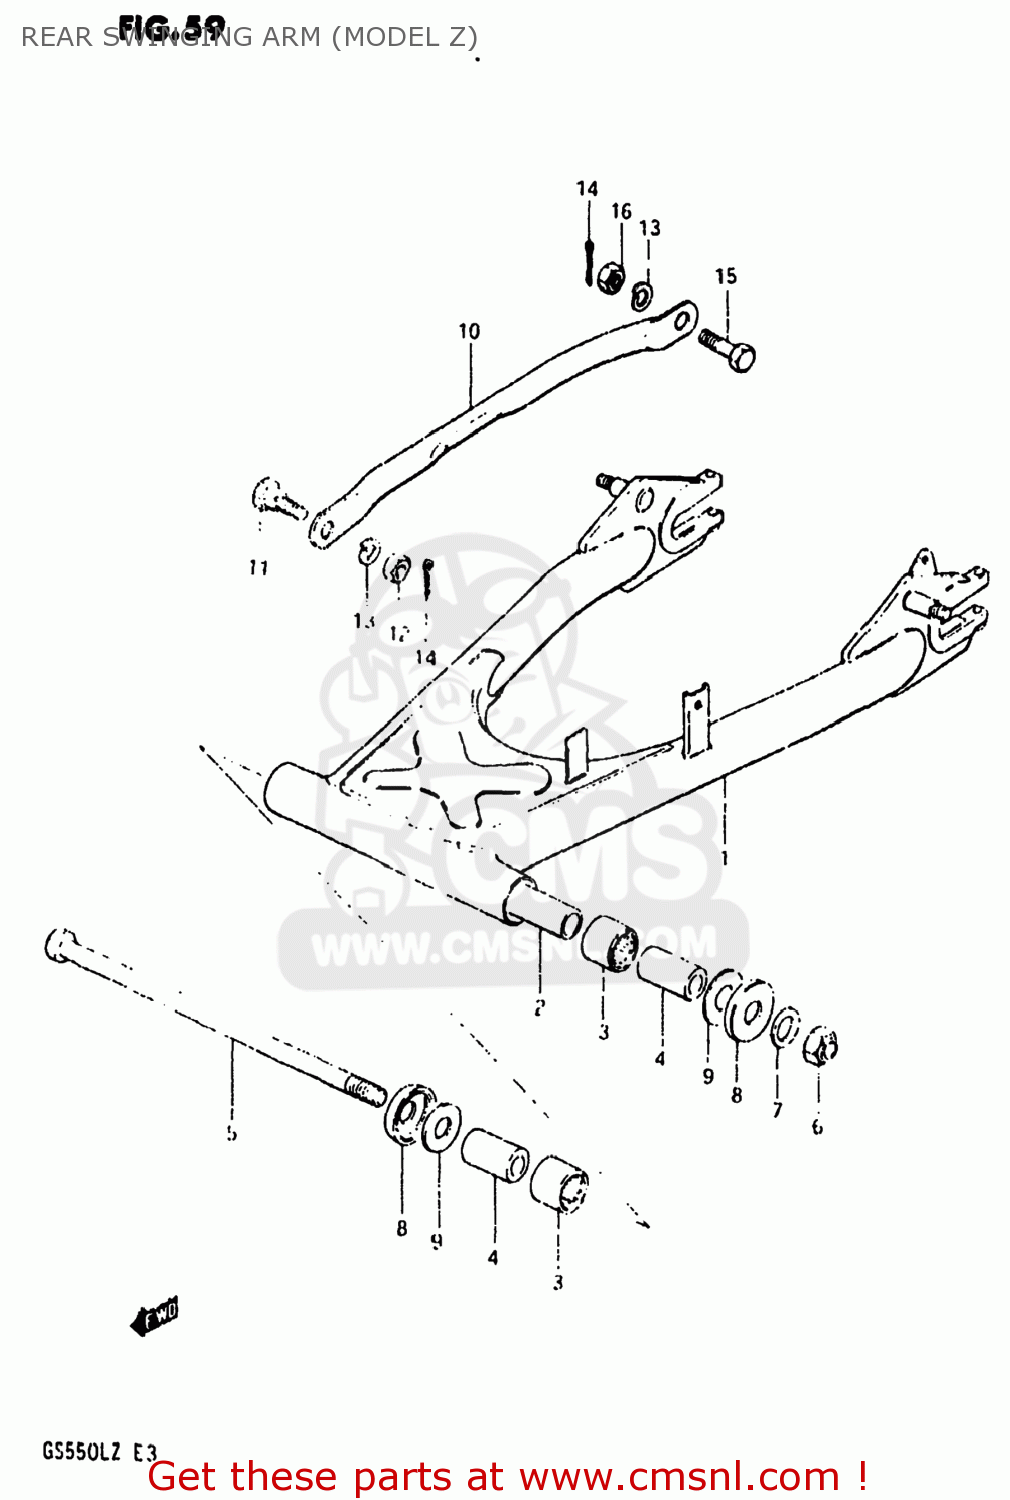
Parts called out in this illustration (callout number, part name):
1	SWING ARM ASSEMBLY,REAR
2	SPACER,RR SWGARM PIVOT CTR
3	BEARING(22X29X30)
4	SPACER,RR SWGARM PIVOT
5	SHAFT,REAR SWING ARM
6	NUT 14MM
7	WASHER
8	CVR,RR SWGARM DUST SEAL(OD:40)
9	WASHER(14.2X34X1)
10	LINK,REAR TORQUE
11	BOLT(10X24.5)
12	NUT
13	LOCK WASHER
14	PIN 20X20
15	BOLT(10X31)
16	NUT
